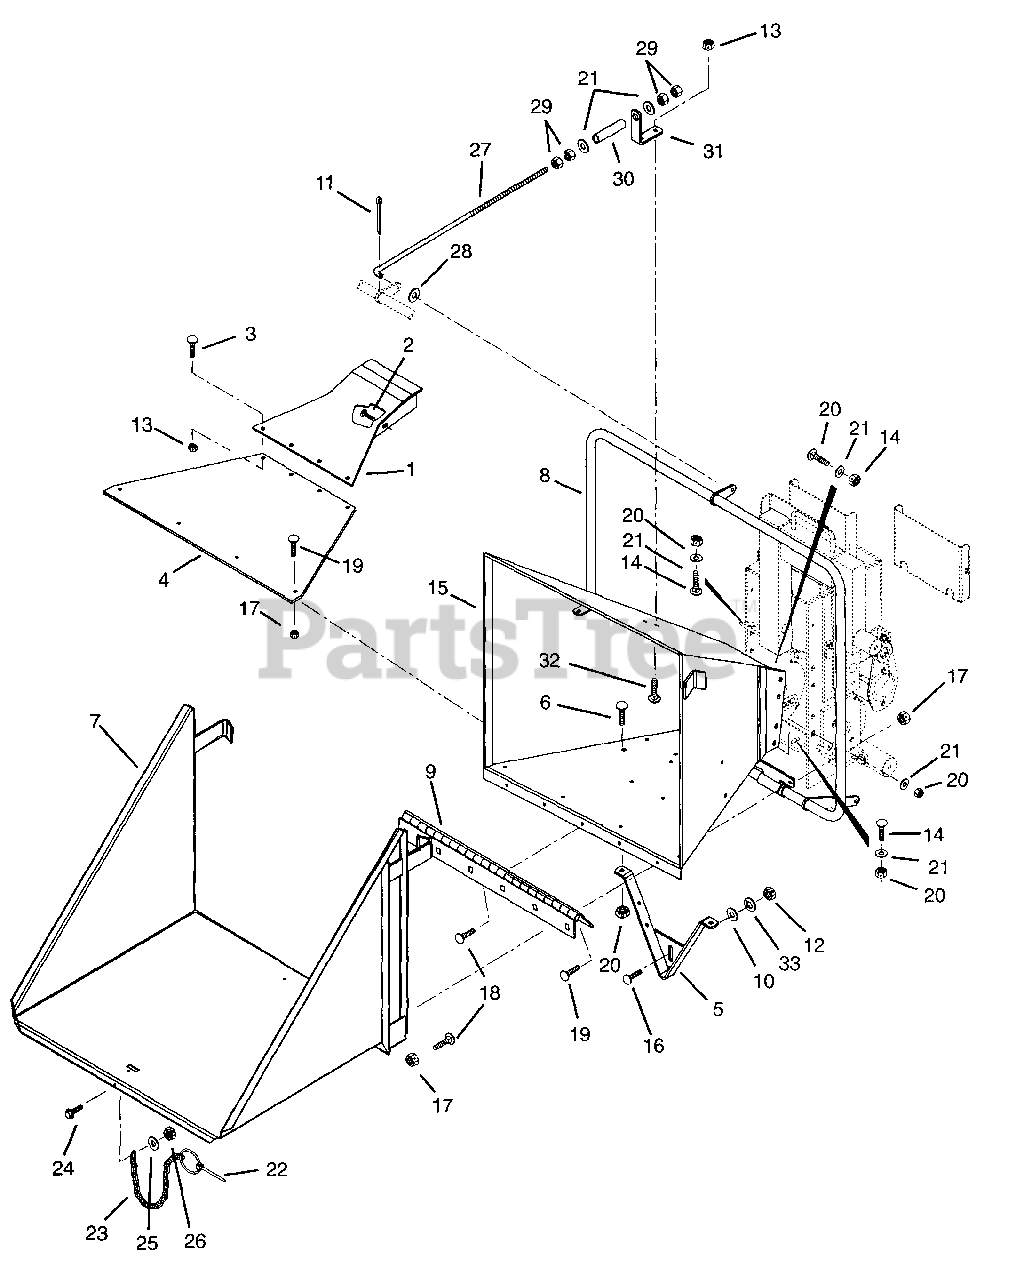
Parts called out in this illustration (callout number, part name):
1	Replacement-Bottom Feed Roll
2	Bolt-Round Head Square Neck .38 X 1.25 Grade 2
3	Bolt-Round Head Square Neck .31-18 X 1.25 Grade 2
4	Plate-Skid-Bottom Feed Roll
5	Pedestal-Hopper Weldment Assembly
6	Bolt-Round Head Square Neck .31-16 X 1.25
7	Apron Weldment
8	Bar-Feed Control Weldment Assembly
10	Washer-Flat-Steel .563 X 1.38 X .109
11	Pin-Cotter .12 X .75
12	Nut-Hex .50-13
13	Nut-Lock-Center .31-18
14	Bolt-Round Head Square Neck .38-16 x 1.00
15	Hopper Weldment
16	Bolt-Round Head Square Neck .50-13 X 1.25 Grade 2
17	Nut-Locking-Center .25-20
18	Bolt-Round Head Square Neck .25-20 X .50 Grade 5
19	Bolt-Round Head Square Neck .25-20 X .75 Grade 2
20	Nut-Locking-Center .38-16
21	Washer-Flat-Steel .438 X 1.00 X .083
22	Pin-Lock .31 X 2.00
23	Chain-5 Straight Link #4
24	Screw-Machine 10-24 w/Insert
25	Washer-Flat-Steel .219 X .50 X .049
26	Nut-Locking-Nylon 10-24 w/Insert
27	Rod-Valve Stop
28	Washer-Flat-Steel .344 X .688 X .065
29	Nut-Hex .38-16
30	Tubing Urethane .438 X .688
31	Bracket-Valve Stop
32	Bolt-Round Head Square Neck .31-18 X .75 Grade 5
33	Washer-Locking .50 x 1.25
